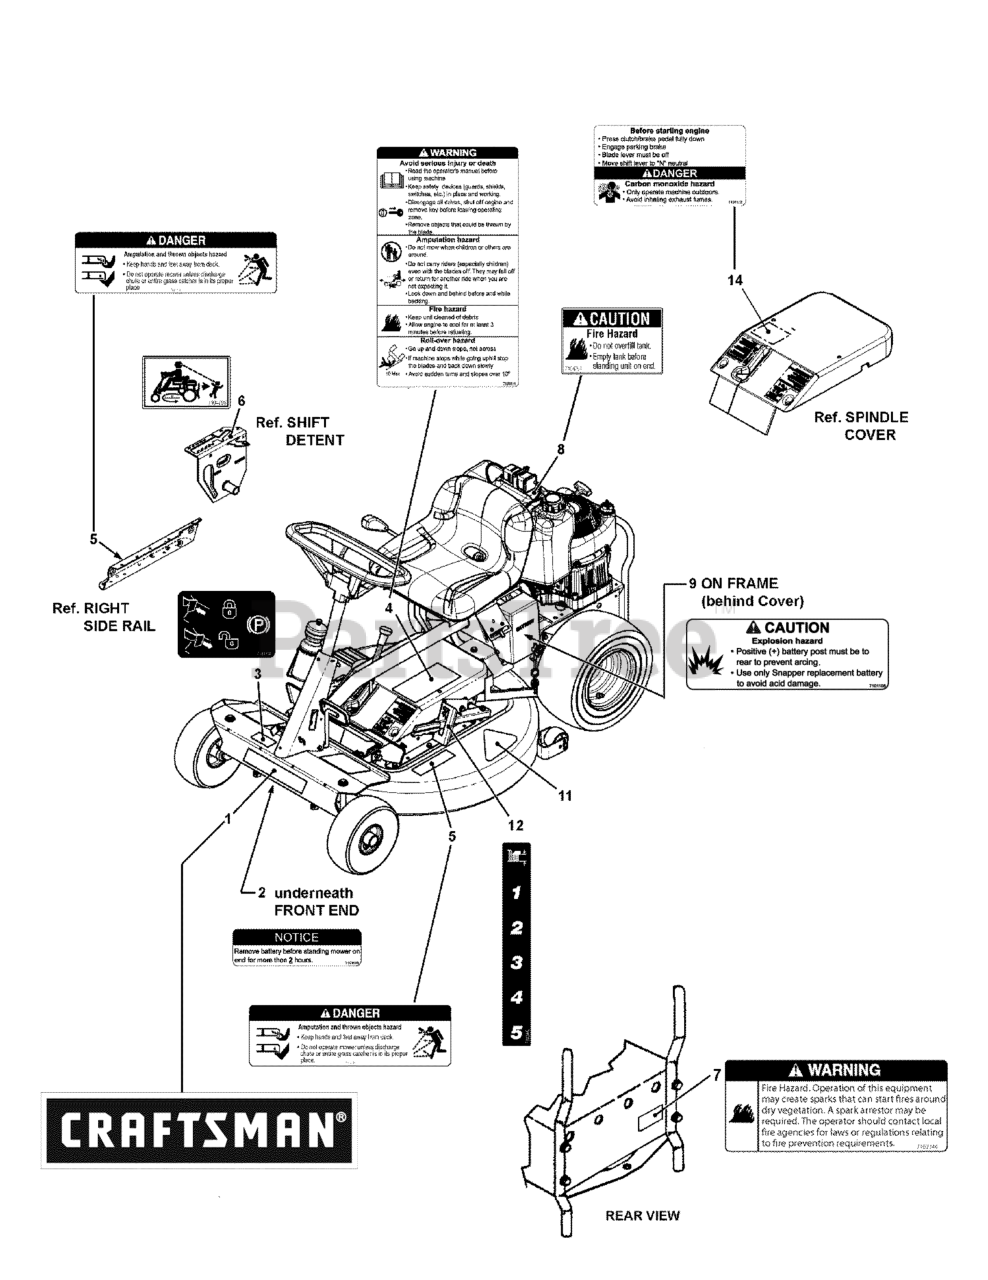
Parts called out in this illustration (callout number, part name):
1	DECAL, Craftsman
2	DECAL, Battery, MY07.5
3	DECAL, ID, Parking Lock
4	DECAL, Safety Panel, Warning, MY07.5
5	DECAL, Danger, Deck, MY07.5
6	DECAL, Reverse Lockout, RER
7	DECAL, Spark Arrestor
8	DECAL, Caution, Fuel Tank, RER
9	DECAL, Important, Battery, Non-Spillable
11	DECAL, 28" Deck
12	DECAL, Height-Of-Cut, Symbol, RER
14	DECAL, Safety, Panel, Danger, MY07.5
